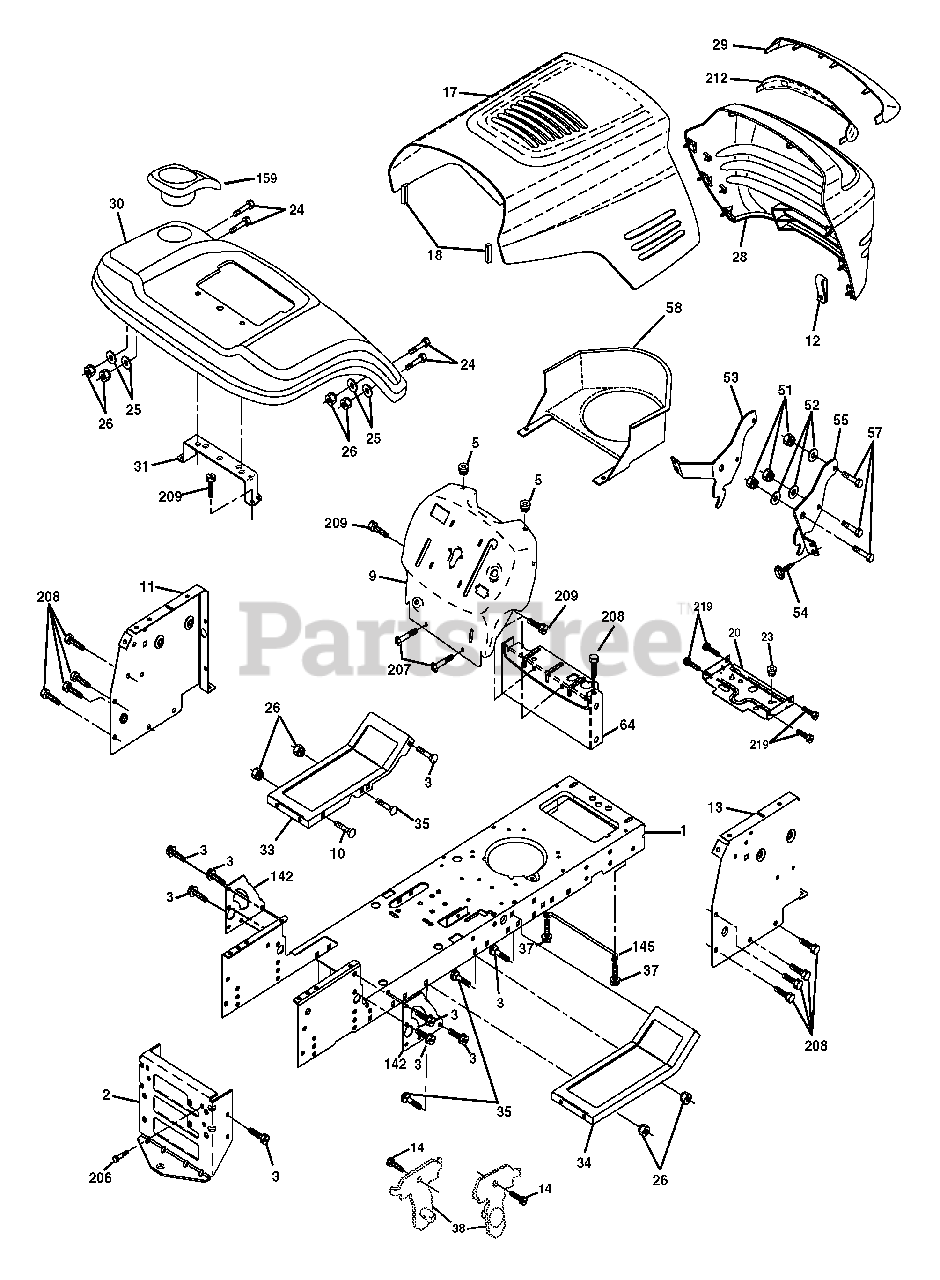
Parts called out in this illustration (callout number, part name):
1	Chassis Stamping
2	Drawbar
3	Screw 3/8-16 x 3/4
5	Bumper Hood/Dash
10	Bolt, Carriage 3/8-16 x 1
11	Panel, Dash, L.H.
12	Clip Tinnerman Grille
13	Panel, Dash, R.H.
14	Screw Thdrol 3/8-16 x 1/2
24	Bolt 3/8-16 x 1 Gr. 5
25	Washer 13/32 x 13/16 x 12 Ga.
26	Nut
28	Grille Lens Asm
29	Lens
31	Bracket, Fender Support
35	Bolt 3/8-16 x 3/4
37	Screw Thdrol 5/16-18 x 1/2 Tyt
38	Bracket Asm. Pivot Mower Rear
51	Nut Lock w/Insert 1/4-20 Unc
52	Washer 9/32 x 7/8 x 16 Ga.
53	Bracket Grille Pick-off LH
54	Screw Hex Wshd. 8-18 x 7/8
55	Bracket Grille Pick-off RH
57	Bolt fin Hex 1/4-20 Unc x .75
64	Dash Lower STLT
142	Plate Reinforcement STLT
145	Jod Pivot Chassis/Hood
159	Cupholder
206	Bolt Shoulder 5/16 -18 TT
207	Screw Thdrol 5/16-18 x 1/2 TYTT
208	Screw Thdrol 3/8-16 x 1/2
209	Screw Hexwsh Thdrol 3/8-16 x 3/4
212	Insert Lens Grille
257	Bumper Hood
